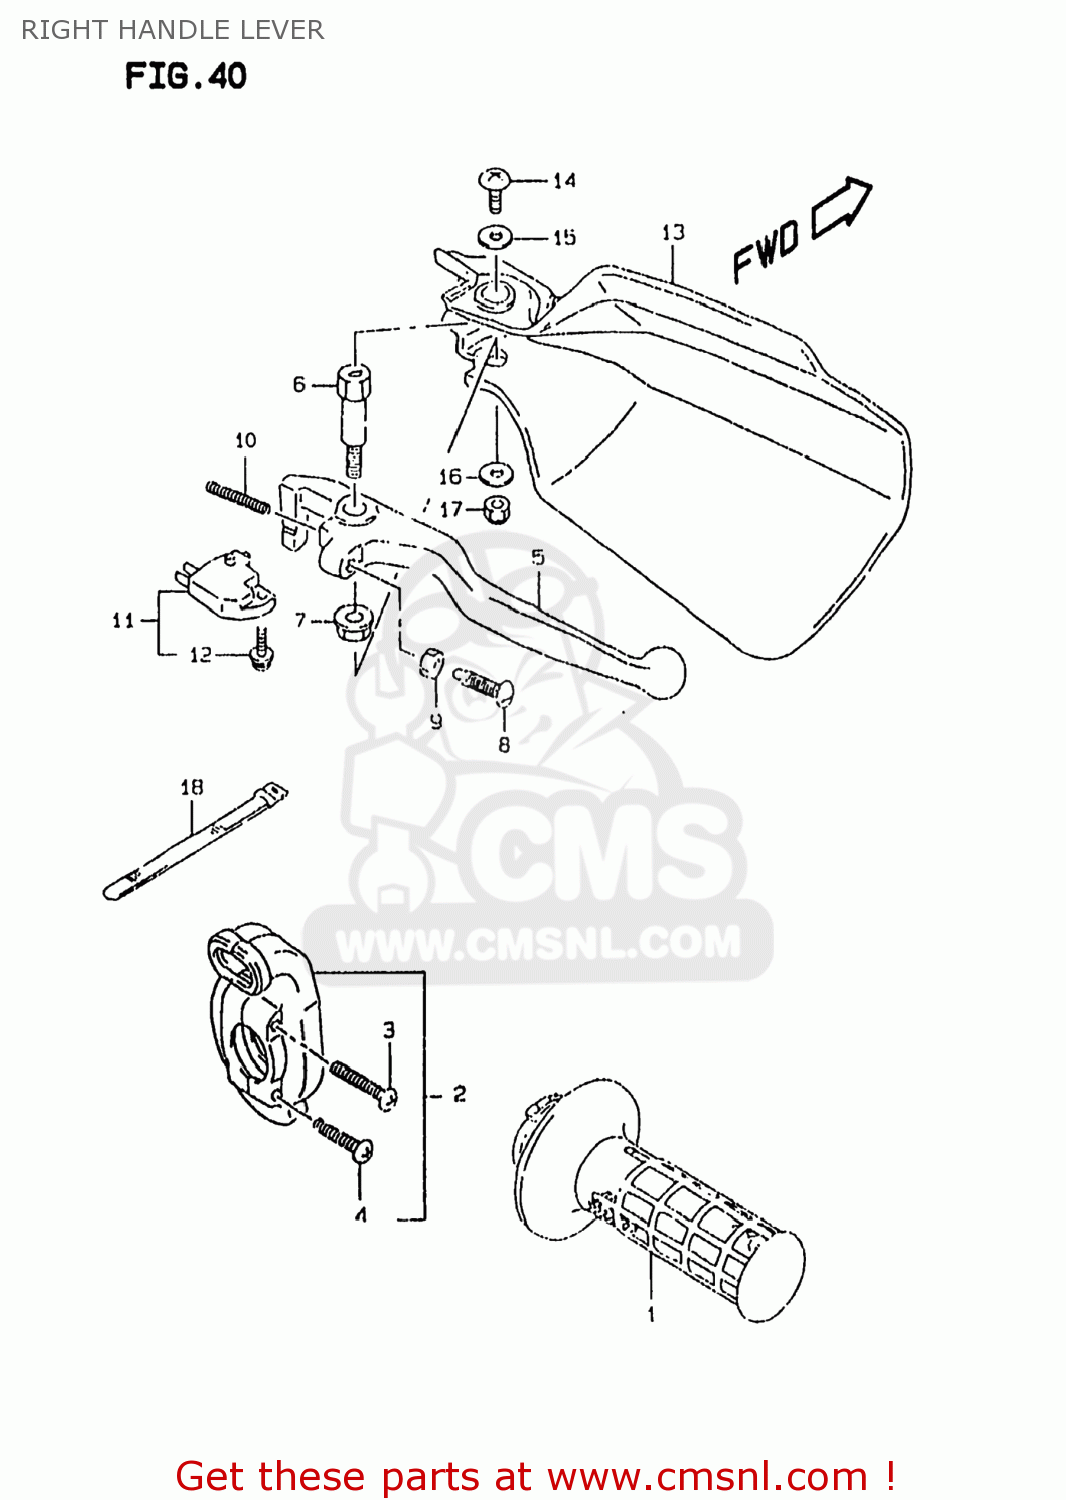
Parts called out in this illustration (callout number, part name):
1	GRIP,THROTTLE
2	CASE ASSY,THROTTLE
3	SCREW(5X25)
4	SCREW
5	LEVER,BRAKE
6	BOLT,BRAKE LEVER PIVOT
7	NUT 6MM
8	BOLT,ADJUST
9	NUT
10	SPRING,RETURN
11	SWITCH ASSEMBLY,STOP
12	SCREW
13	COVER,KNUCKLE,R
14	SCREW
15	WASHER(5.5X16X1.2)
16	WASHER(6.5X16X1.6)
17	NUT 6MM
18	CLAMP(L:120)
